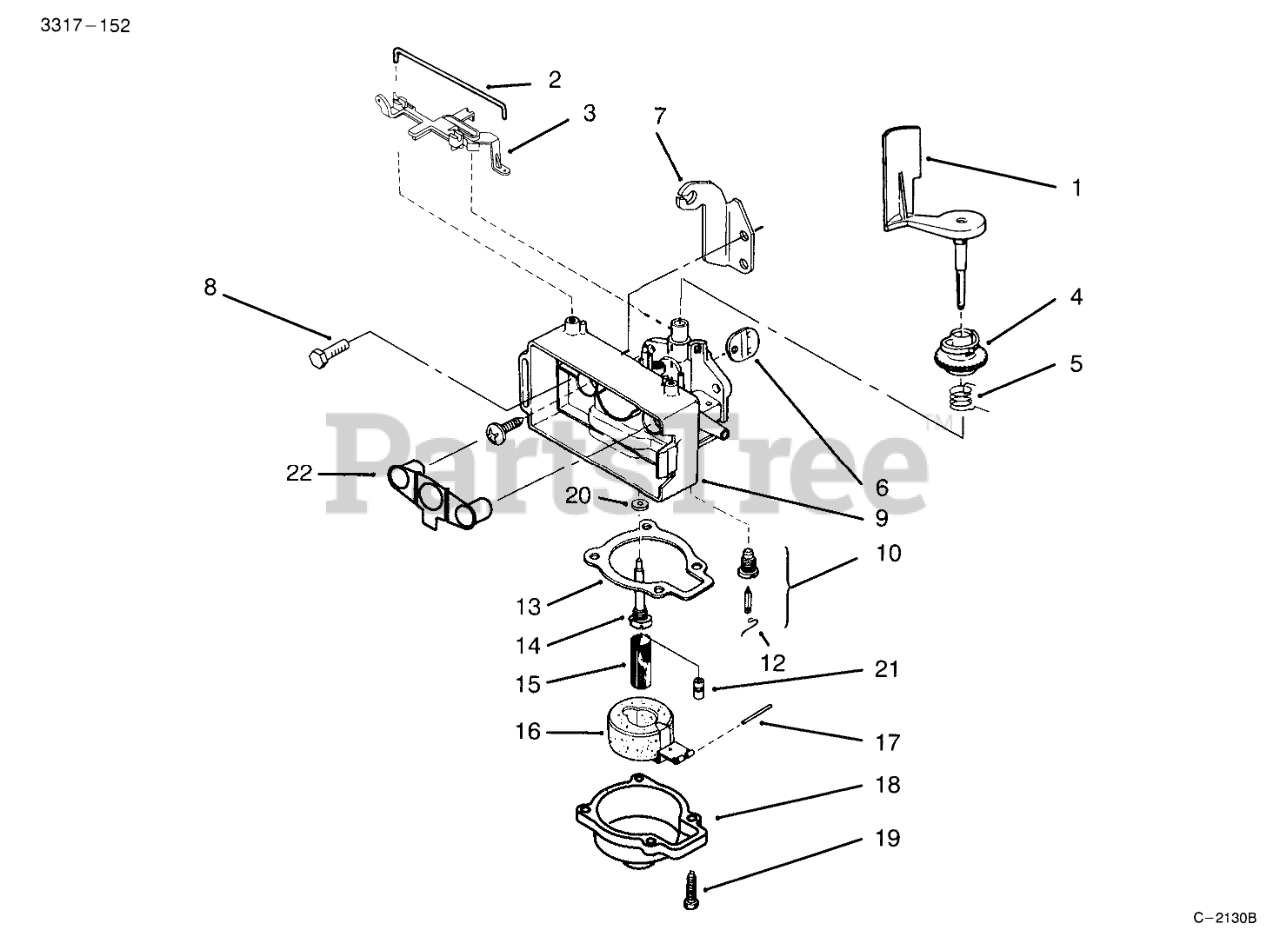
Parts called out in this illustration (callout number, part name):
1	Air Vane&shaft
2	RETAINER
3	LEVER-ADJ. VF
4	COLLAR-ADJUST, AIRVANE
5	SPRING-GOV V
6	DISC-THRO. V
7	BRKT-THRO.CONT V
8	SCREW V
9	Carburetor Body
10	Kit-Float Valve,Body & Seat (Incl Ref. #12)
14	NOZZLE VF
15	FILTER-FUEL VS
16	FLOAT & ARM ASM
17	PIN-STRAIGHT
18	CHAMBER-FLOAT
19	SCREW-HH
20	WASHER
21	JET-MAIN VF
22	SHIELD-FUEL V
